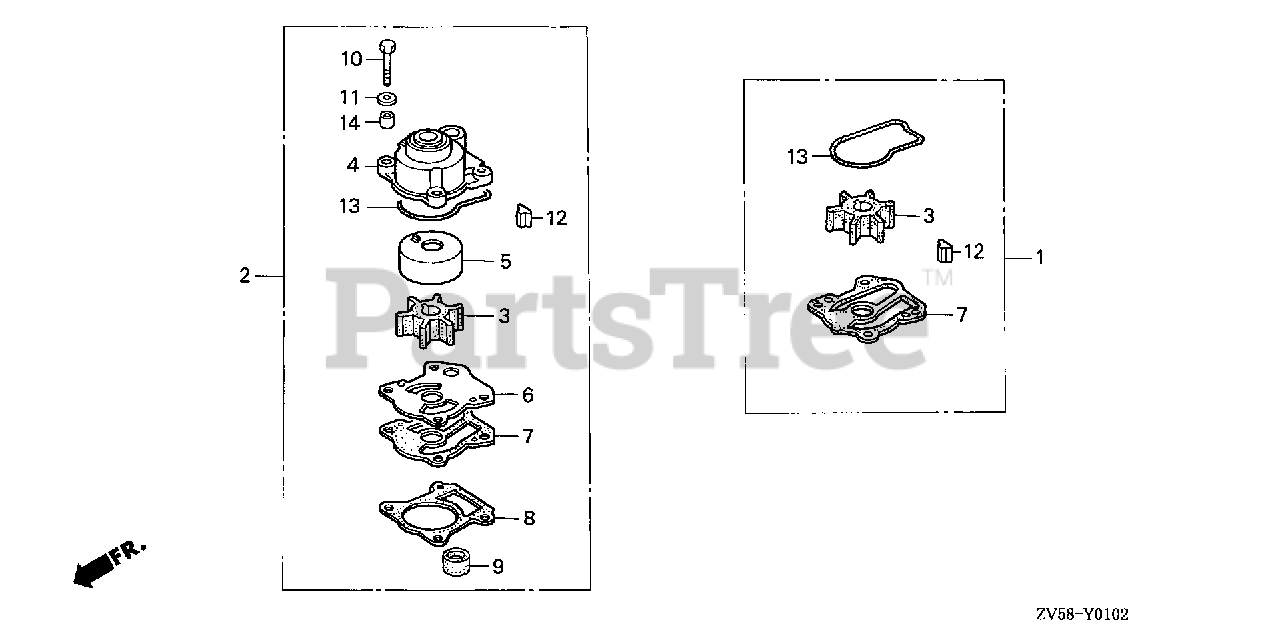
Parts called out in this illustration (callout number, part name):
1	PUMP KIT, IMPELLER
2	PUMP KIT, IMPELLER (INCLUDES IMPELLER HOUSING)
3	IMPELLER, PUMP
4	HOUSING, IMPELLER
5	LINER, PUMP
6	COVER, IMPELLER
7	GASKET B, IMPELLER
8	GASKET, WATER PUMP
9	RING, WATER TUBE SEAL
10	BOLT, HEX. (6X40)
11	WASHER (6MM)
12	KEY, WOODRUFF
13	O-RING, WATER PUMP
14	COLLAR, IMPELLER HOUSING
